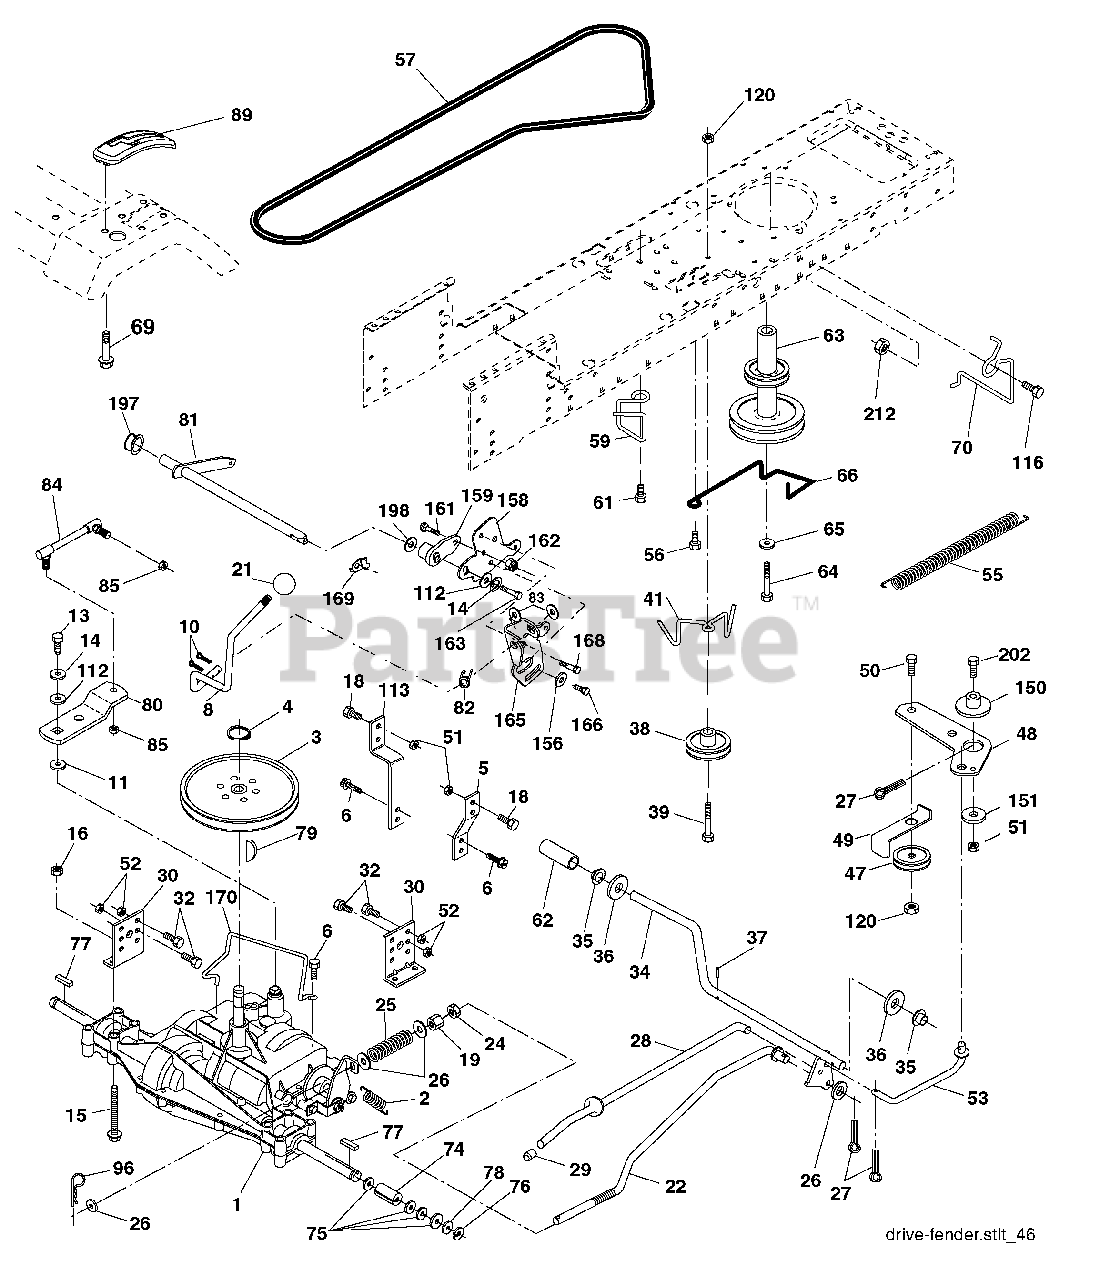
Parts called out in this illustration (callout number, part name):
2	Spring Return Brake T/a Zinc
3	Pulley Transaxle 18" tires
4	Ring Retainer # 5100-62
5	Strap Torque 30 Degrees
6	Screw 5/16-18 x 3/4
8	Rod Shift Fender Adjust Lt
10	Pin Cotter 1/8 x 1 Cad
11	Washer Plate Shf 388 Sq Hole
13	Bolt 1/4-28 unf Gr. 8 W/Patch
14	Washer Lock Hvy Helical
15	Bolt Hex FLGHD 5/16-18 Gr. 5
16	Nut Lock Hex w/ins 5/16-18
18	Bolt, Fin Hex 3/8-16 unc x 1 Gr. 5
19	Nut Lock 3/8-16 unc
21	Knob
22	Rod Brake Blk Zinc 26 840
24	Nut Hex Jam 3/8-16 unc
25	Spring Rod Brake 2 00 Zinc
26	Washer 13/32 x 13/16 x 16 Ga.
27	Pin Cotter 1/8 x 3/4 Cad
28	Rod Brake Parking LT/YT
29	Cap Brake Parking
30	Bracket Mtg Transaxle
32	Bolt Hex Hd 5/16-18 unc x 3/4
34	Shaft Asm Pedal Foot
35	Bearing Nylon Blk 629 Id
36	Washer 21/32 x 1 x 16 Ga.
37	Pin Roll 3/16 x 1"
38	Pulley Composite Flat
39	Bolt RDHD 3/8-16 unc x 2-3/4 Gr. 5
41	Keeper Belt Flat Idler
47	Pulley Idler V Groove Plastic
48	Bellcrank Asm
49	Retainer Belt Style Spring
50	Bolt Carr. Sh. 3/8-16 x 1-1/2 Gr. 5
51	Nut Crownlock 3/8-16 unc
52	Nut Crownlock 5/16-18 unc
53	Link Clutch
55	Spring Return Clutch 6 75
56	Screw 3/8-16 x 1-1/4
57	V-Belt Ground Drive 95 30
59	Keeper Belt Span Ctr
61	Screw 3/8-16 x .875
62	Cover Pedal Blk Round
63	Engine Pulley
64	Bolt Hex
65	Washer Lock Hvy Hlcl Spr 7/16
66	Keeper Belt Engine Foolproof
69	Screw Hex wsh HiLo 1/4 x 1/2 unc
70	Guide Belt Mower Drive RH
74	Spacer Axle
75	Washer 25/32 x 1 1/4 x 16 Ga.
76	E-ring #5133-75
77	Key Square 2 0 x 1845/ 1865
78	Washer 25/32 x 1-5/8 x 16 Ga.
79	Key Woodruff #9 3/16 x 3/4
80	Arm Shift
81	Shaft Asm Cross Tapered PMST/20
82	Spring Torsion T/a
83	Washer 17/32 x 3/4 x 16 Ga.
84	Link Transaxle Dana/18" Zinc
85	Nut Lock Center 1/4 - 28 FNTHD
89	Console Shift STLT
96	Retainer Spring 1"
112	Washer 9/32 x 3/4 x 10 Ga.
113	Strap Torque LT
116	Bolt Rdhd Sq Neck 3/8-16 x 1
120	Nut Lock Flg. 3/8-16 unc
150	Spacer Retainer
151	Washer 13/32 x 2 x 10
156	Washer Srrted 5/16ID x 1.125
158	Bracket Shift Mount
159	Hub Tapered Flange Shift Lt
161	Bolt Rdhd Sqnk 1/4-20 x 3/4
162	Nut Crownlock 1/4-20 unc
163	Bolt Hex Fin 1/4-20 unc x 1 Gr. 5
165	Bracket Pivot Lever
166	Screw 5/16-18 x 5/8
168	Bolt Shoulder 5/16-18 x .561
169	Plate Fastening
170	Keeper Belt Transaxle Gear
197	Nyliner Snap-In
198	Washer Nyliner
202	Bolt RdHd 3/8-16 unc x 1-3/4 Gr. 5
212	Nut Hexfl ange Lock
